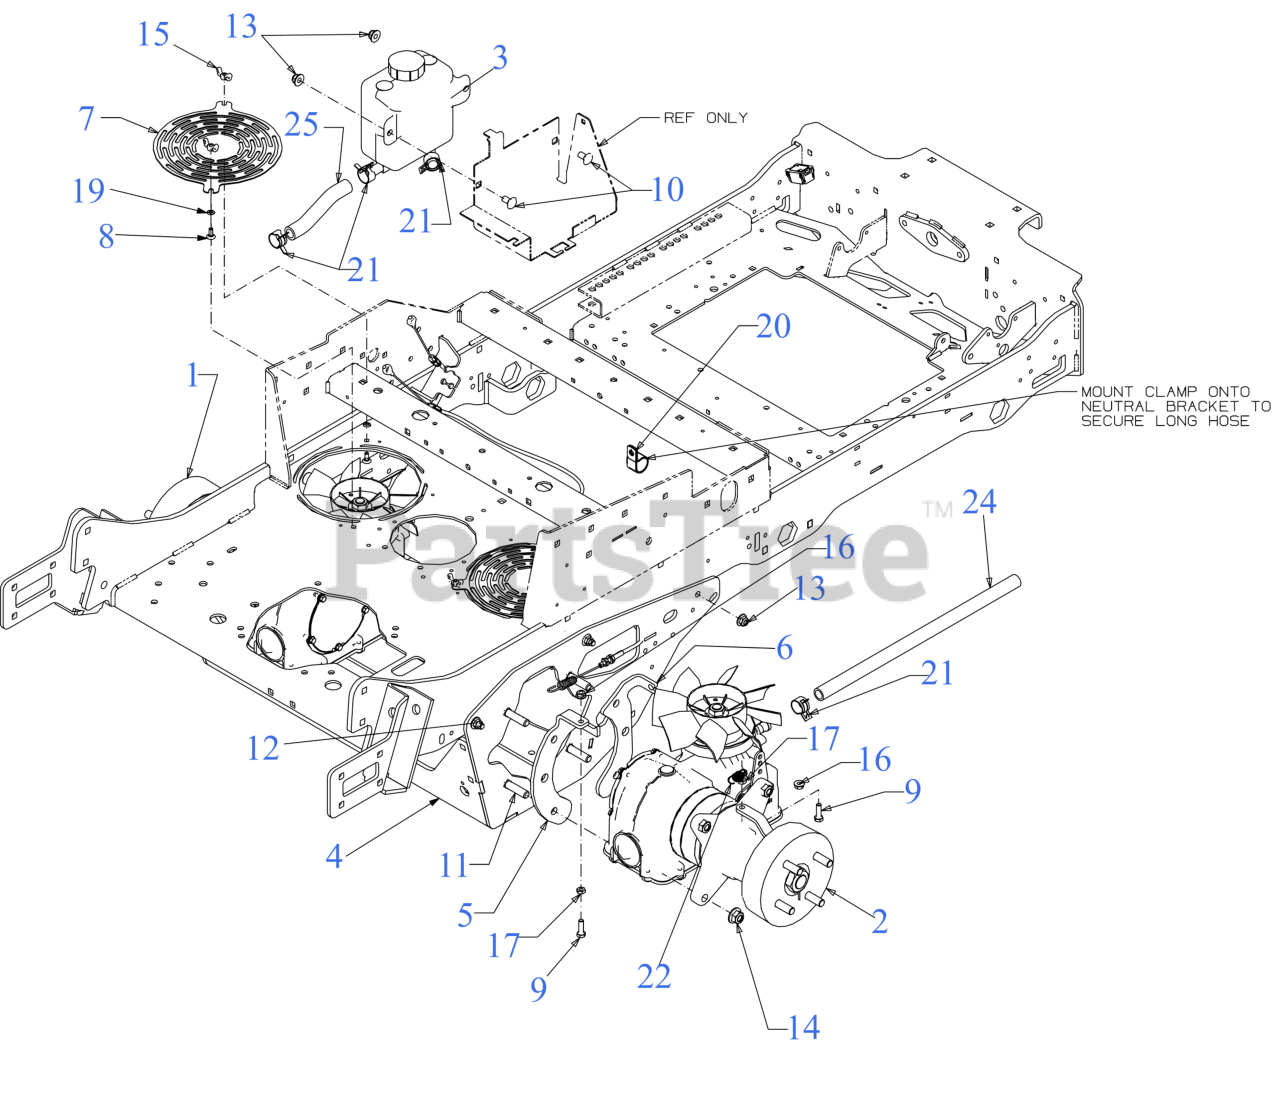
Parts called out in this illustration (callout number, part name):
1	TRANSMISSION ASSEMBLY PARKER (LH)
2	TRANSMISSION ASSEMBLY PARKER (RH)
3	HYDRO TANK ASSEMBLY
4	TRANSMISSION MOUNTING BRACKET
7	TRANSMISSION COVER PLATE
8	CARRIAGE BOLT 1/4-20 x .62
9	SCREW 5/16-18 x 1.0 GR5
10	CARRIAGE BOLT 3/8-16 x .750 GR5
11	CARRIAGE BOLT 1/2-13 GR5
12	CARRIAGE BOLT 3/8-16 X1.25 GR5
15	WING NUT 1/4-20
16	HEX FLANGE NUT
19	RETAINER-BOLT .25ID x .50OD
20	HOSE CLAMP 1.0"
21	HOSE CLAMP
22	EXTENSION SPRING .500 OD x 1.71
24	OIL HOSE 5/8 ID x 18.00 LG
